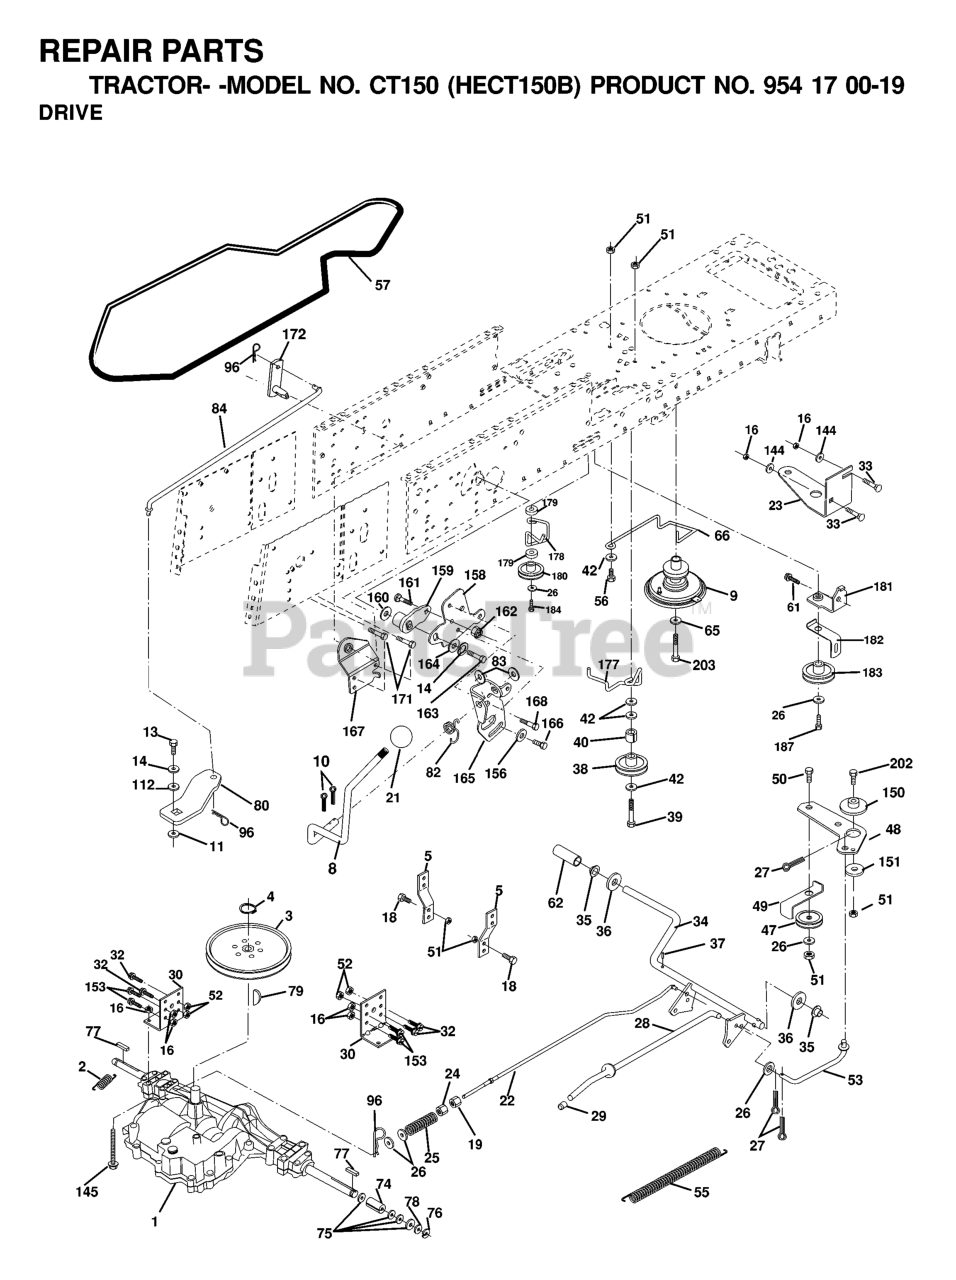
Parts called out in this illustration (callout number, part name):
2	SPRING,BRAKE RETURN
3	PULLEY
4	RETAINING RING LT
5	STRAP TORQUE
8	ROD.SHIFT.FENDER.ADJ.LT.CRD
9	CLUTCH ASSY
10	PIN COTTER
11	WASH-SHFT PLT LT
13	BOLT 1/4-28X3/4
14	LOCKWASHER
16	NUT.71038.31-18.HEX.NYLOCK
18	BOLT
19	NUT
20	BOLT HEX
21	KNOB.DUCKHEAD.1/2
23	Bracket Pnt Clutch Noram
24	NUT
25	SPRING ROD LT
26	WASHER
27	COTTER PIN
28	ROD BRAKE PARK LT
29	PLUNGER CAP
30	BRACKET TRANSAXLE
32	BOLT
33	Bolt Rdhd Sqnk 5/16-18 Unc x 3/4
35	BEARING.NYLON
36	WASHER LT
37	DRIVE PIN
38	PULLEY.FLAT
42	WASHER
47	IDLER PULLEY
48	BELLCRANK, CLUTCH
49	RETAIN BELT
50	BOLT
52	LOCKNUT
53	LINK, CLUTCH LT
55	SPRING, RETURN LT
61	SCREW 3/8-16X3/4
62	COVER, PEDAL (1 2)
65	LOCKWASHER
66	KEEPER BELT ENGINE
74	SPACER AXLE
77	SQUARE KEY
79	KEY STD (1373) DANA
82	SPRING,TORSION
83	WASHER
96	RETAINER M
112	WASHER LT
145	BOLT
150	BUSHING.BELLCRANK.GRD.DR
151	WASHER 12/32X2X10GA
153	BOLT RB
156	WASHER.SRRTD.5/16
158	BRACKET
159	HUB
161	BOLT
162	NUT.CROWNLOCK.1/4
163	BOLT
164	Washer 5/8 x .281 x 10 Ga.
165	RP BRACKET
167	BRACKET.SUPT.SHIFT.CRD
168	BOLT.SHOULDER.5/16-18X
171	SCREW LT
172	SHAFT
180	PULLEY.FLAT.IDLER
181	BRKT.IDLER.GRD.DR.CRD
182	KEEPER BELT
183	PULLEY.V-IDLER
184	SCREW.HXWSH.3/8
187	SCREW
198	WASHER.NYL.7/8IDX.105"HYD CR
202	BOLT.3/8-16X1.50
203	BOLT.HEX.7/16-20 X 5
